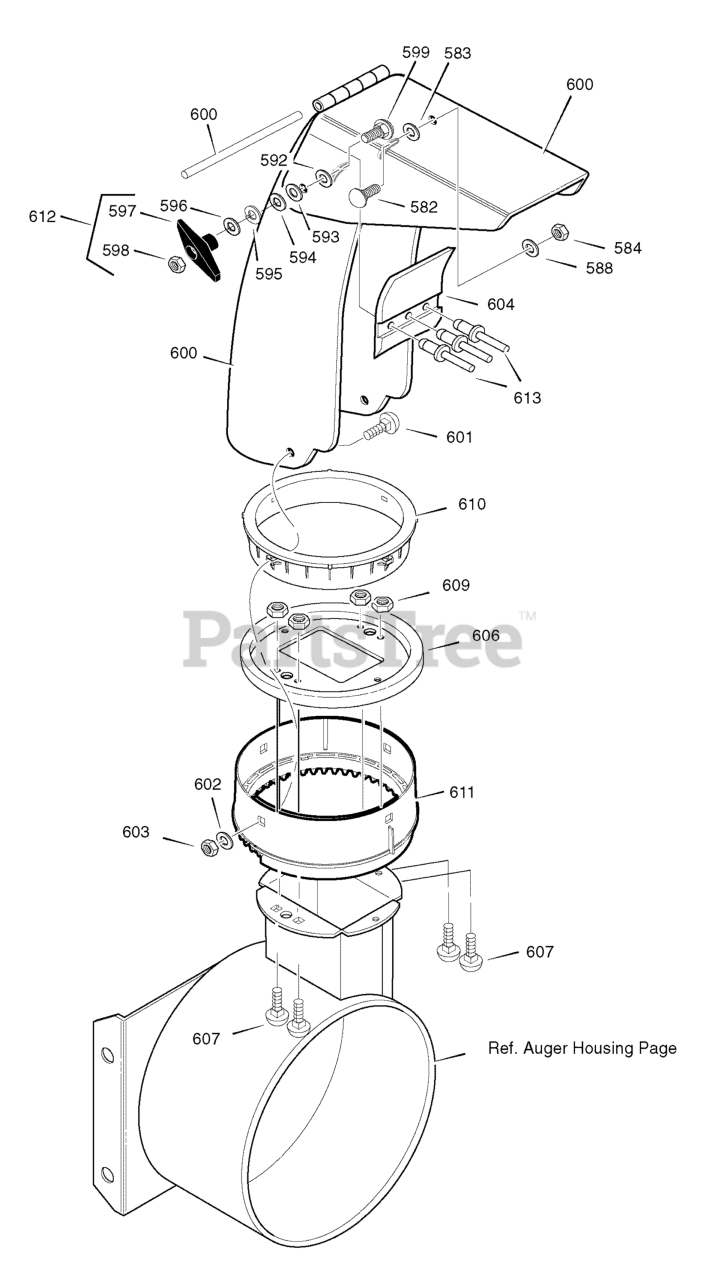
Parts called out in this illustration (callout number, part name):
582	BOLT, Carriage, 5/16 - 18 x 3/4
583	WASHER, Plastic
584	NUT, Hex Nylock, 5/16 - 18
588	WASHER, Plastic
592	WASHER, Plastic
593	WASHER, Plastic
594	WASHER, Flat
595	WASHER, Split
596	WASHER, Flat
598	NUT, Hex, 5/16 - 18
599	BOLT, 5/16 - 18 x 1
600	CHUTE ASSEMBLY
601	Bolt, Carriage, 5/16 - 18 x 1
602	WASHER, Flat
603	NUT, Hex Nylock, 5/16 - 18
604	FLAP, Chute
606	CHUTE COLLAR
607	SCREW, 1/4 - 20 x 3/4
609	NUT, Hex Nylock, 5/16 - 18
610	RETAINER RING, Inner
611	RETAINER RING, Outer
612	KNOB & NUT
613	RIVET, Pop
